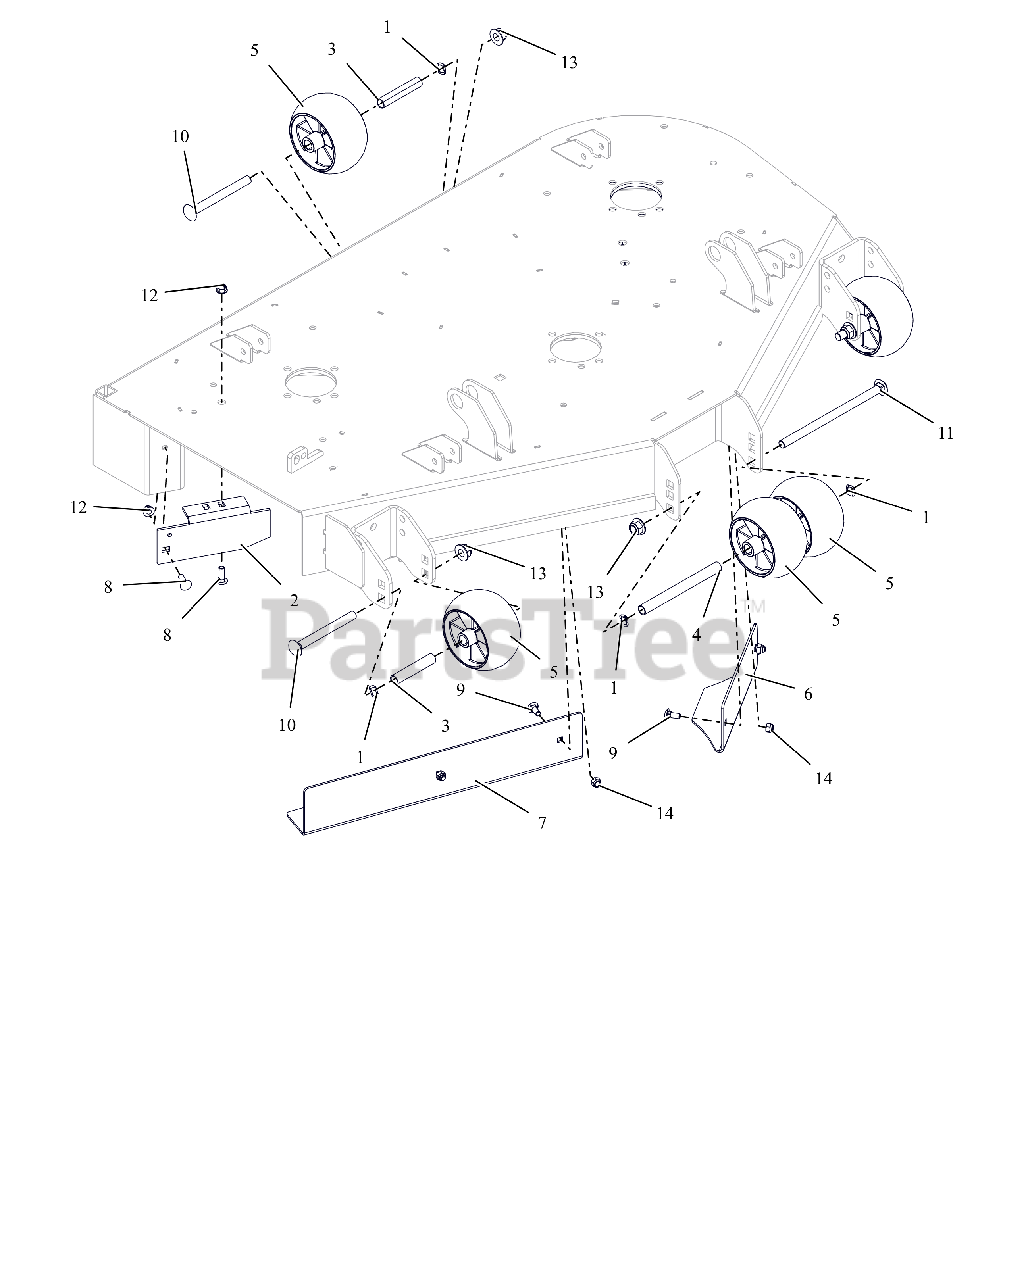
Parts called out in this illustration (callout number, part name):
1	WAVE WASHER .531X.781X.125FH
2	44"-48" SIDE DISCH BAFFLE -RED
3	SPACER, .510X.625X3.35
4	SPACER, .510X.625X6.50
5	ANTI-SCALP WHEEL - 5X3 CTR
6	BAFFLE, 44/48" LH VACUUM (RED)
7	BAFFLE, 44" RH VACUUM (RED)
8	BLT,RHSN .31-18X1.00 G5 ZCC
9	BLT,RHSN .31-18X.75 G5 ZCC
10	BLT, RHSN .50-13X5.00 G5 ZCC
11	BLT, RHSN .50-13X8.50 G5 ZCC
12	NUT,NYL-FLG .31-18 GF ZCC
13	NUT,NYL-FLG .50-13 GF ZCC
14	NUT,NYL .31-18 G5 ZCC
